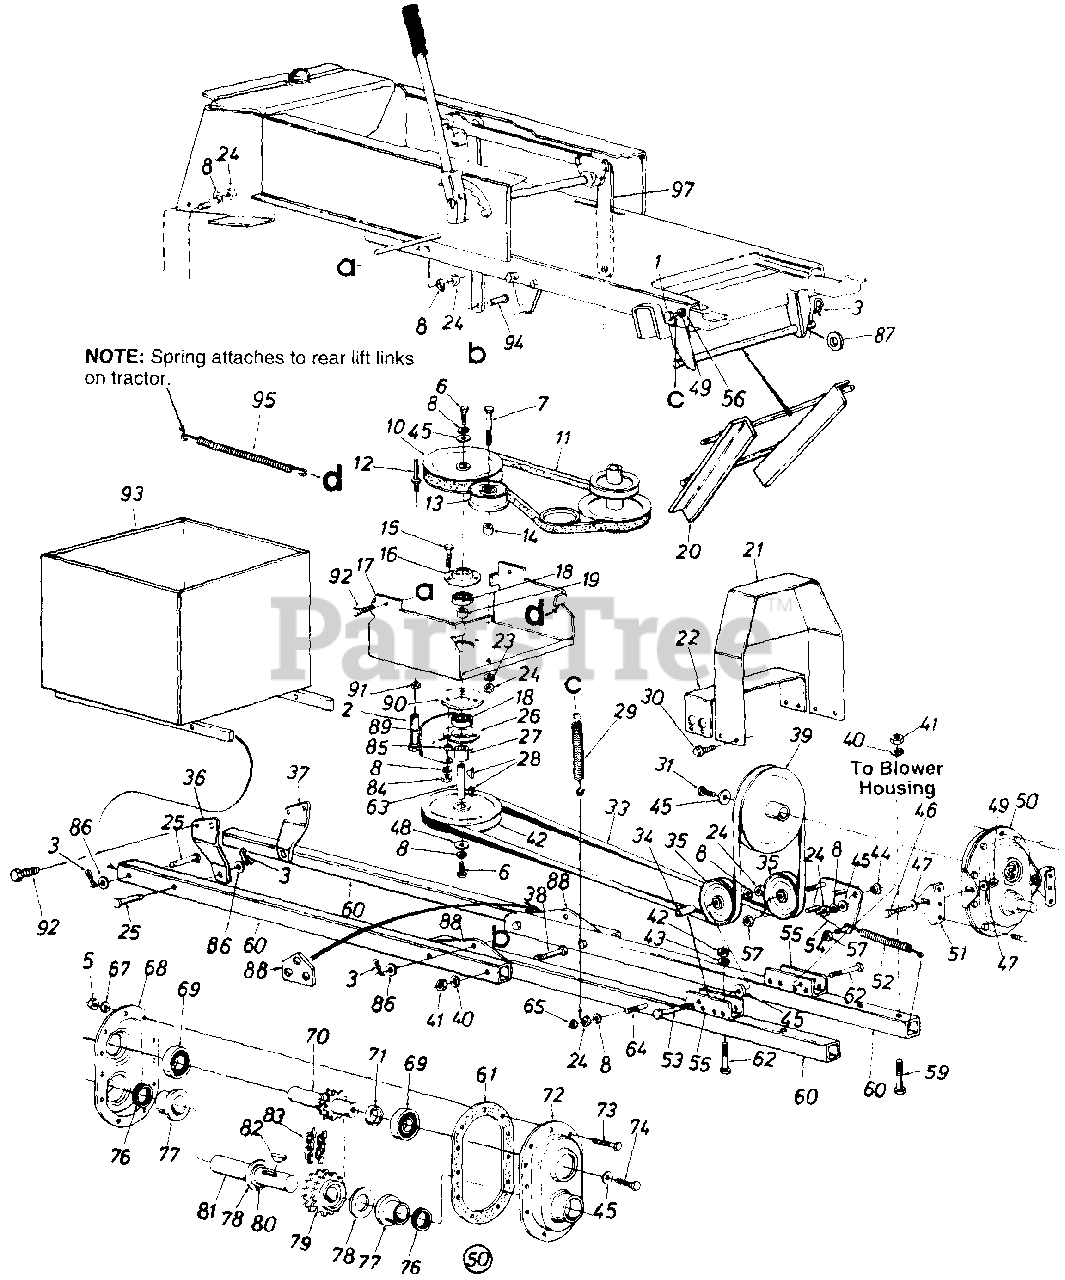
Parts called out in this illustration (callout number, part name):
1	Hex Bolt 5/16-18 x 2" Lg.
2	Clevis Pin Spec. 3/8" Dia. x 2.62" Lg.
3	Intern. Cot. Pin
5	Hex Nut 1/4-28 Thd.
6	Hex L-Scr. 3/8-24 x 1.0" Lg.
7	Hex Bolt 3/8-16 x 2.25" Lg.
8	L-Wash. 3/8" I.D.
10	5/8" "V"-Pulley .79" I.D. x .65" O.D.
11	"V"-Belt
12	Belt Guard Pin
13	Fl-Idler 3.75" O.D.
14	Spacer. 385"1.D. x.63" O.D. x .76"
15	Hex Bolt 5/16-24 x 1.50
16	Open Brg. Hsg.
19	Spacer .8" I.D. x 1" O.D.
20	Guide Brkt. Ass'y.
21	Belt Cover Ass'y.
22	Belt Cover Brkt.
24	Hex Jam Nut 3/8-16 Thd.
25	Clevis Pin .50" Dia. x 1.75" Lg.
26	Brg. Hsg. Ass'y.
27	Spacer .8" I.D. x 1" 0.D. x .125"
28	Woodruff Key 3/16" x 5/8" HT
29	Extension Spr. 6.44" Lg.
30	Hex Wash. HD-Tap Scr. 5/16-18 x .50
31	Hex L-Scr. 3/8-24 x 1.0" Lg.
33	"V"-Belt
34	Spacer .39" I.D. x .62" O.D. x 1.74" Lg.
35	V-Idler Pulley
39	5/8" "V"-Pulley 7.5" O.D.
40	L-Wash. 1/2" I.D.
41	Hex Nut 1/2-13 Thd.
42	5/8" "V"-Pulley
44	Shld. Spacer
45	Fl-Wash..4" I.D. x 1.25" O.D. x .16"
46	Hex Bolt 5/16-18 x 1.25" Lg.
47	Bell-Wash..345" I.D. x .88" O.D. x .06"
49	Hex Nut 5/16-18 Thd.
50	Comp. Chain Gear Box Ass'y.
51	Gear Box Support Brkt.
52	Exten. Spring .6" Lg.
53	Hex Bolt 3/8-16 x 3.5" Lg.
56	L-Wash. 5/16" I.D.
57	Hex Nut 3/8-24 Thd.
59	Hex Bolt 1/2-13 x 3" Lg.
60	Sq. Tubing 43" Lg.
61	Gasket
62	Hex Bolt 3/8-16 x 3" Lg.
63	Shaft -.787" Dia. x 3.81" Lg.
64	Hex Bolt 3 8-24 x 3" Lg.
65	Hex L-Nut 3/8-16 Thd.
67	Wave Spring Wash..27" I.D. x .51" O.D. x .03"
68	Complete Gear Hsg. Half - L.H.
69	Ball Brg. 1" I.D. x 2" O.D.
70	11-2 x .5 Pitch Sprocket Shaft Ass'y.
71	Spacer 1" I.D. x 1.18" O.D. x .44"
72	Comp. Gear Hsg. Half - R.H.
73	Hex Bolt 1/4-28 x 1" Lg.
74	Hex L-Scr. 3/8-24 x 1" Lg.
76	Oil Seal 1.25" I.D.
77	Flange Brg. 1.25" I.D.
78	Fl -Wash. 1.25" I.D. x 2" O.D. x .036"
79	DBL Sprocket 19-2 Teeth x .5" Pitch
80	Snap Ring for 1.25" Dia. Shaft
81	Gear Shaft 1.25 Dia. x 6" Lg.
82	Hi-Pro Key 1/4" x 7/8"
83	40-2 Chain 1/2" Pitch x 25 Links
83	Master Link #40 Type IV
84	Hex Nut 5 16-24 Thd.
85	Spacer .380" I.D. x .625" O.D. x .227
86	Fl-Wash..53" I.D. x 1" O.D. x .06"
87	Fl-Wash..62" I.D. x .93" O.D.
88	Attaching Plate (46" Decks)
90	Spindle Spacer
91	Hex L-Nut 1/4-20 Thd.
92	Hex Bolt 3/16 x 1" Lg.
93	Weight Box Ass'y.
95	Extension Spring
97	Deck Lift Link Ass'y.
